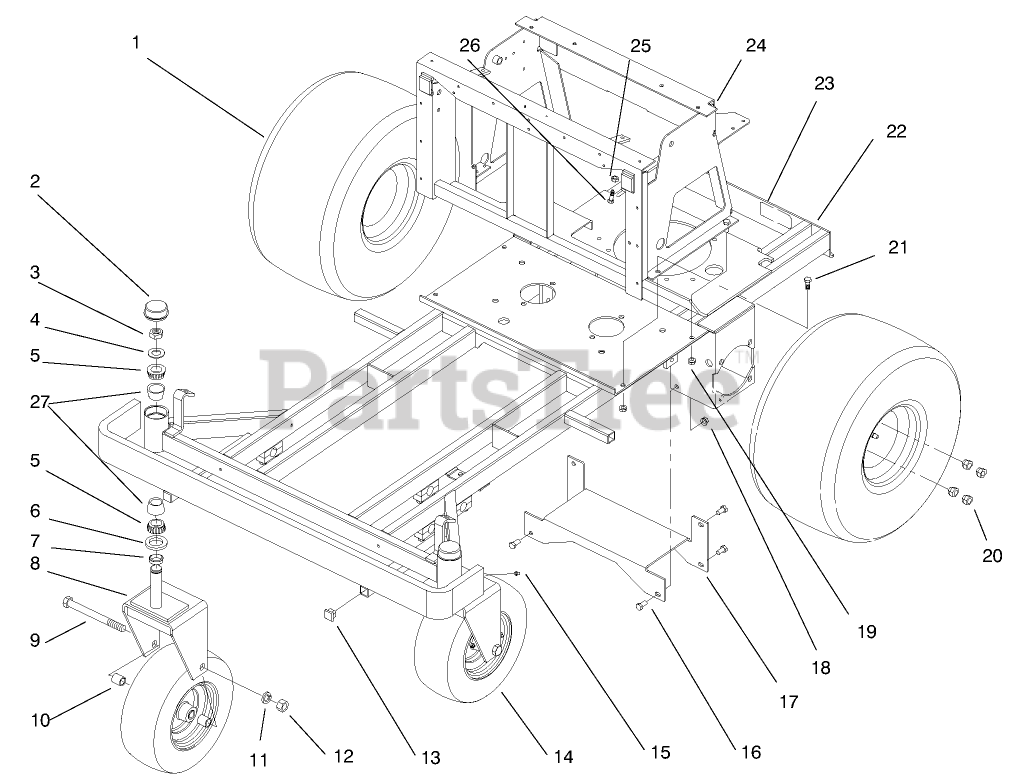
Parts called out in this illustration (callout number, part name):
1	ASSEMBLY - WHEEL/TIRE
2	CAP-DUST
3	NUT-LOCK, NI
4	WASHER-FLAT
5	BEARING-CONE, TAPERED
7	SPACER
8	Castor ASM
9	SCREW-HH
10	SPACER
11	WASHER-LOCK
12	NUT-HEX
13	PLUG-SQUARE PLASTIC
14	Wheel And Tire ASM
15	FITTING-GREASE
16	SCREW-HH
17	Bracket-Motor
18	NUT-FLANGE
19	NUT-LOCK, NI
20	NUT-LUG
21	SCREW-HH
22	Frame ASM
23	DECAL-WARNING, HOT SURFACE
24	Seat Frame ASM
25	NUT-HEX
26	SCREW-HH
27	BEARING-CUP, TAPERED
